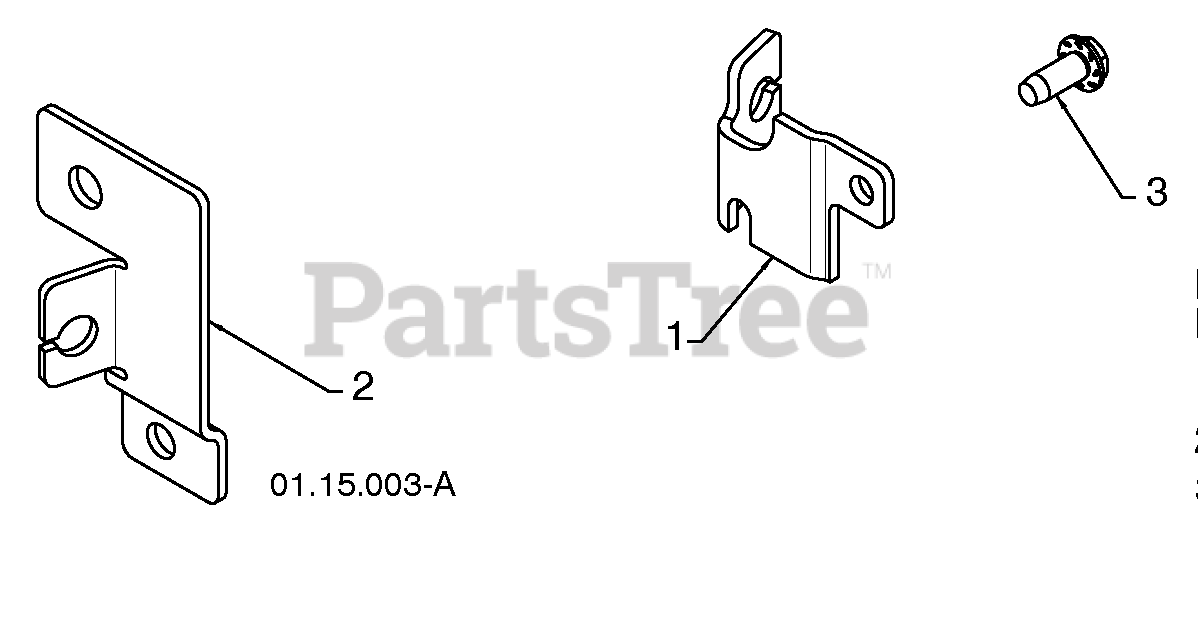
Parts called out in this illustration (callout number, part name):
1	CABLE BRACKET LH
2	CABLE BRACKET RH
3	SCREW 1/4-20 X .625
